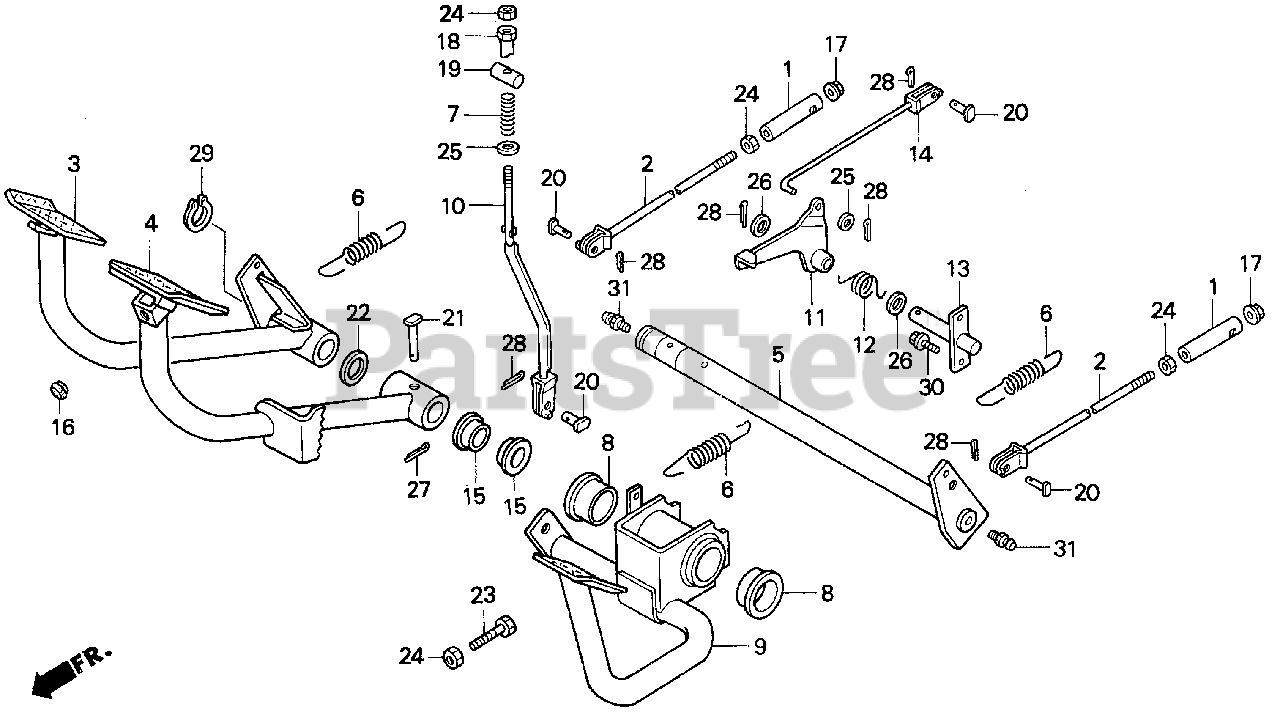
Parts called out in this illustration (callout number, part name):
1	JOINT (8MM)
2	ROD B, RR. BRAKE
3	PEDAL, R. BRAKE
4	PEDAL, L. BRAKE
5	SHAFT, BRAKE
6	SPRING, CLUTCH PEDAL
7	SPRING, CLUTCH ROD
8	BUSH, CLUTCH PEDAL
9	PEDAL, CLUTCH
10	ROD, CLUTCH
11	PEDAL, DIFFERENTIAL LOCK
12	SPRING, DIFFERENTIAL LOCK PEDAL
13	PIVOT, DIFFERENTIAL LOCK
14	ROD, DIFFERENTIAL LOCK
15	BUSH, BRAKE PEDAL
16	RUBBER B, STOPPER
17	NUT, HEX. (8MM)
18	NUT, ADJUSTING
19	PIN, CLUTCH LEVER
20	PIN (8X17.5)
21	PIN, BRAKE SHAFT
22	WASHER, THRUST (24.1X36X1.5)
23	BOLT, CAP (8X25)
24	NUT, HEX. (8MM)
25	WASHER, PLAIN (8MM)
26	WASHER, PLAIN (14MM)
27	PIN, COTTER (2.0X15)
28	PIN, COTTER (2.5MM)
29	CIRCLIP (OUTER) (24MM)
30	BOLT, FLANGE (8X20)
31	FITTING, GREASE (A.76)
